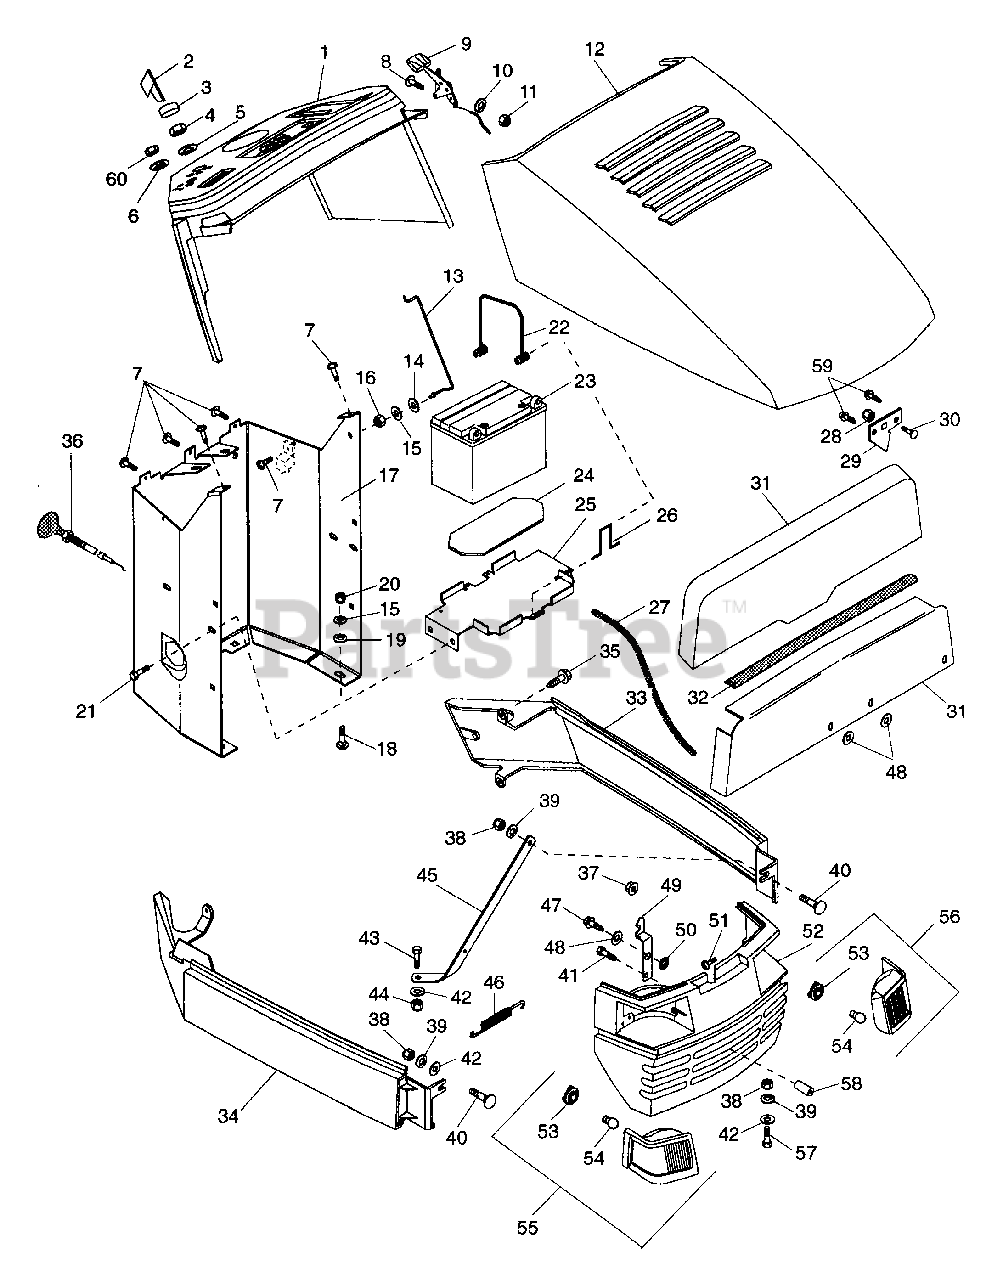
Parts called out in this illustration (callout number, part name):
1	DASH PANEL
2	KEY -W/CAP
3	CAP - IGNITION SWITCH
4	NUT- PANEL .562-24 GRECO
5	WSHR-LK-INT .563X.040 PL
6	WSHR-FL-STL .520X.827X.062 YZ
7	SCR-TAP 10-24X.375 CRPH 1A
8	SCR-MCH 10-24X.50 SLRH PL
9	THROTTLE CONTROL
10	WSHR-LK 10X.047 MED PL
11	NUT-HEX 10-24 PL
13	HOOD PROP ROD
14	WAVE WASHER .390X.655X.110
15	WSHR-FL-STL.312X.734X.065PL
16	NUT-LK-CTR .250-20 PL
17	DASH TOWER
18	BLT-RDHDSQNK.31-18X.75GR5SHTPL
19	WSHR-LK .312X.097 PL HVY
20	NUT-HEX .312-18
21	SCR-TAP .312-18X.50 HWH PL TR
22	BATTERY STRAP
23	BATTERY W/ TUBE
23	BATTERY W/TUBE
24	RUBBER PAD
25	BATTERY SUPPORT
27	DRAIN HOSE
28	NUT-FLG. .312-18 PL
29	HOOD CATCH
30	BLT-RDHDSQNK .31-18X.50 GR5 PL
31	BAFFLE- HOOD 15/16.5HP
31	BAFFLE- STEEL
32	RUBBER SEAL 15IN
33	L.H. UPPER PANEL
34	R.H. UPPER PANEL
35	SCR-TAP 10-12X.50 CRPH PL A BL
36	CHOKE CABLE
37	NUT-SELF-THRDNG FITS.25 STUDPL
38	NUT-HEX .375-16
39	WSHR-LK .375X.094 MED PL
40	BLT-RDHDSQSHNK .38-16X1.00 PL
41	BLT-HEX .25-20X.50 PL GR2
42	WSHR-FL-STL.406X.812X.065PL
43	BLT-HEX .38-16X.75 PL GR2
44	NUT-LK-CTR .375-16 GR A PL
45	GRILLE SUPPORT
46	SG-TENS .035X.45X2.75 WLD 3.5
47	SCR-TAP 12-24X.75 HWH PL TR
48	WSHR-FL-STL .281X1.250X.048PL
49	HOOD LATCH
50	BSHG-FLG .500X.625X.148
51	SCR-TAP 10-12X.62 CRPH PL A
53	LAMP SOCKET
54	HEADLIGHT BULB, 1156
55	HEADLIGHT- R.H.
56	HEADLIGHT- L.H.
57	BLT-HEX .38-16X1.00 PL
58	SPACER - TAPPED NYLON
59	SCR-TAP 10-12X.50 CRPH PL A BL
60	NUT .50-28
